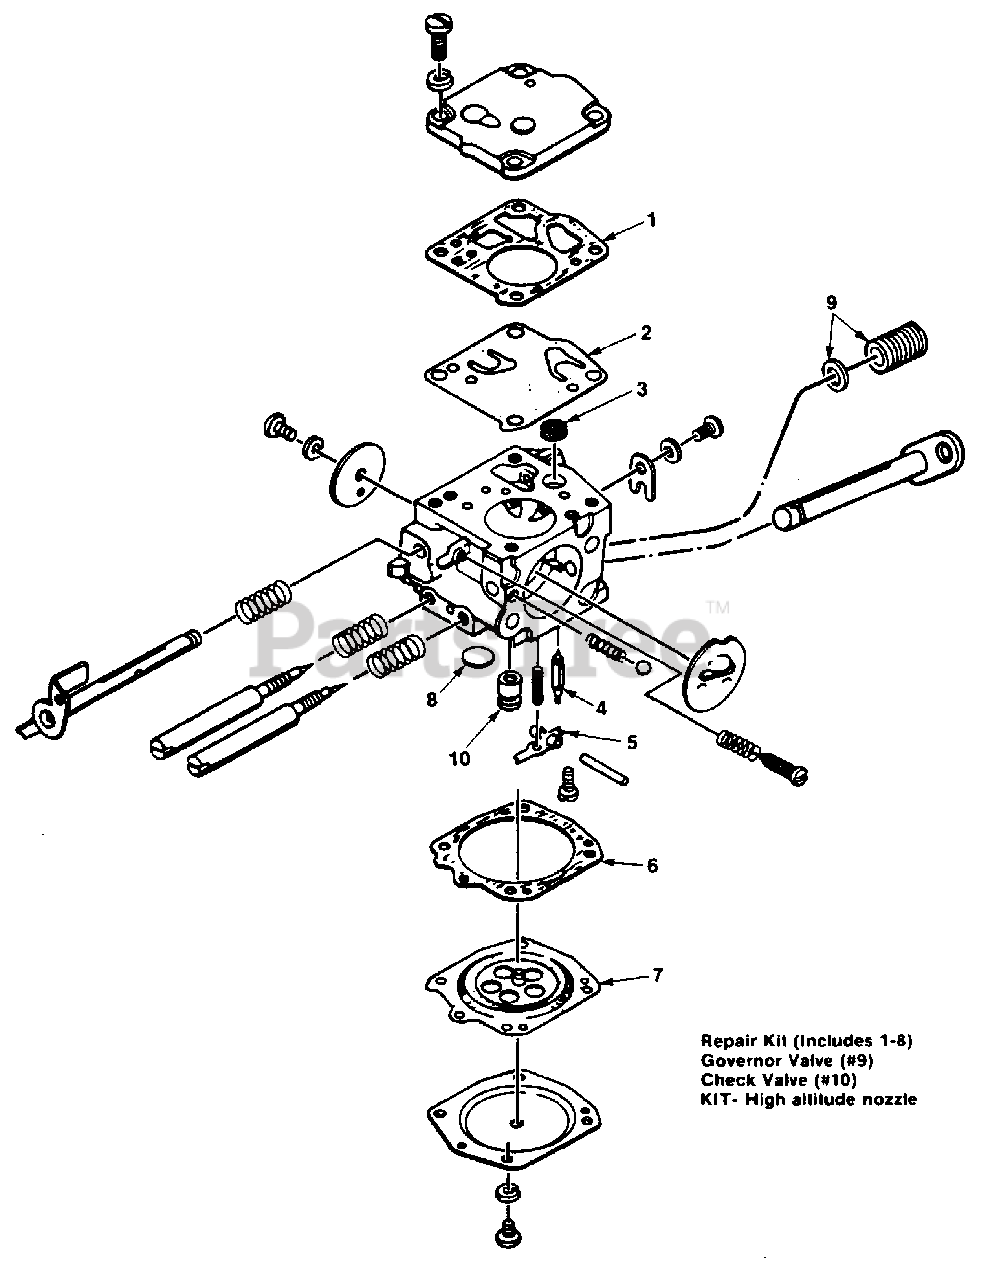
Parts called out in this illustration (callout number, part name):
1	Repair Kit
2	Repair Kit
3	Repair Kit
4	Repair Kit
5	Repair Kit
6	Repair Kit
7	Repair Kit
8	Repair Kit
9	Governor Valve
10	Check Valve
